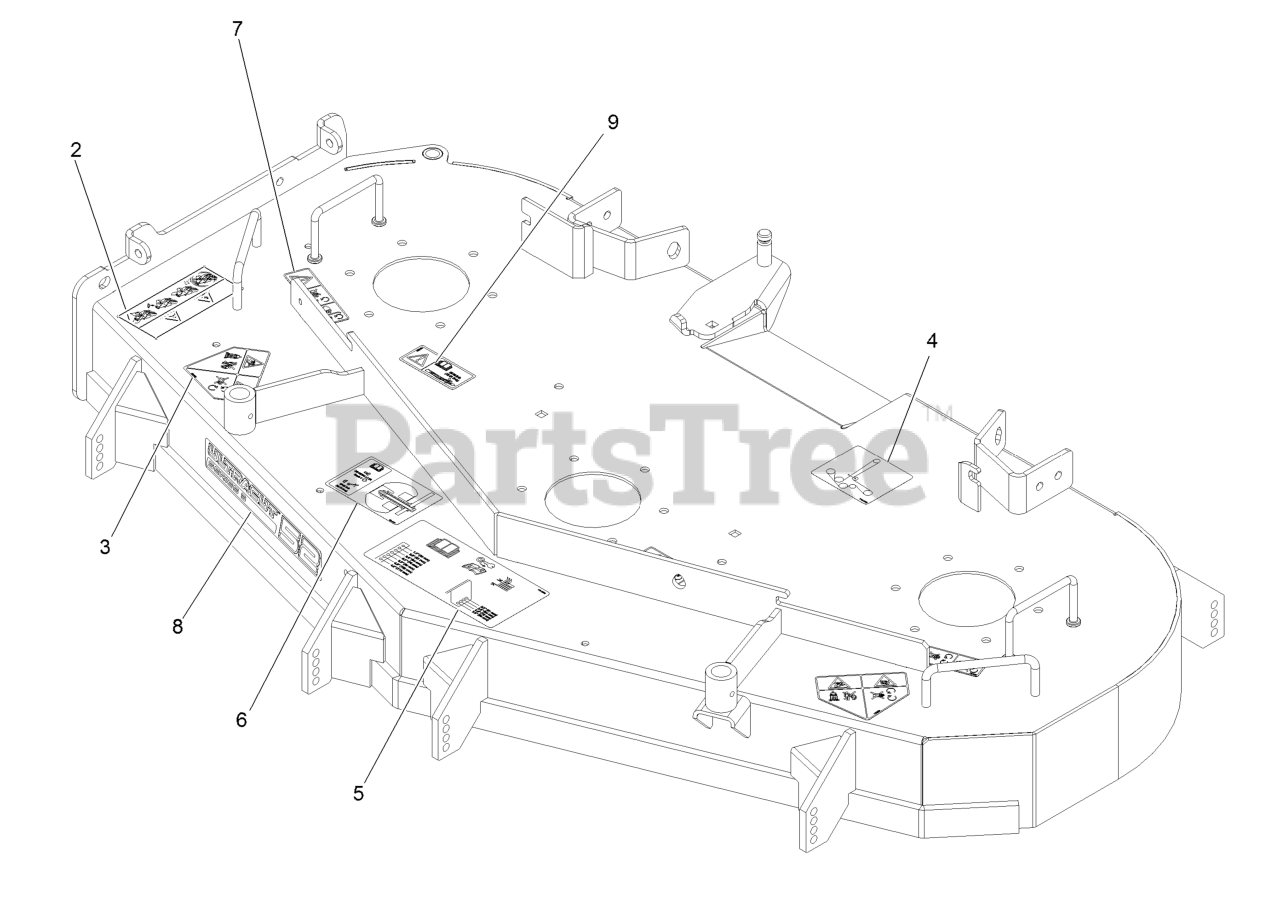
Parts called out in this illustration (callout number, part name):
2	Decal-Warning, Bagger
3	Decal-Danger
4	Decal-Belt Routing
5	Decal-Anti-Scalp
6	Decal-Roller Mounting
7	Decal-Cover, Missing
8	Decal-Ultracut 52 Series 3
9	Decal-Bolt Torque
